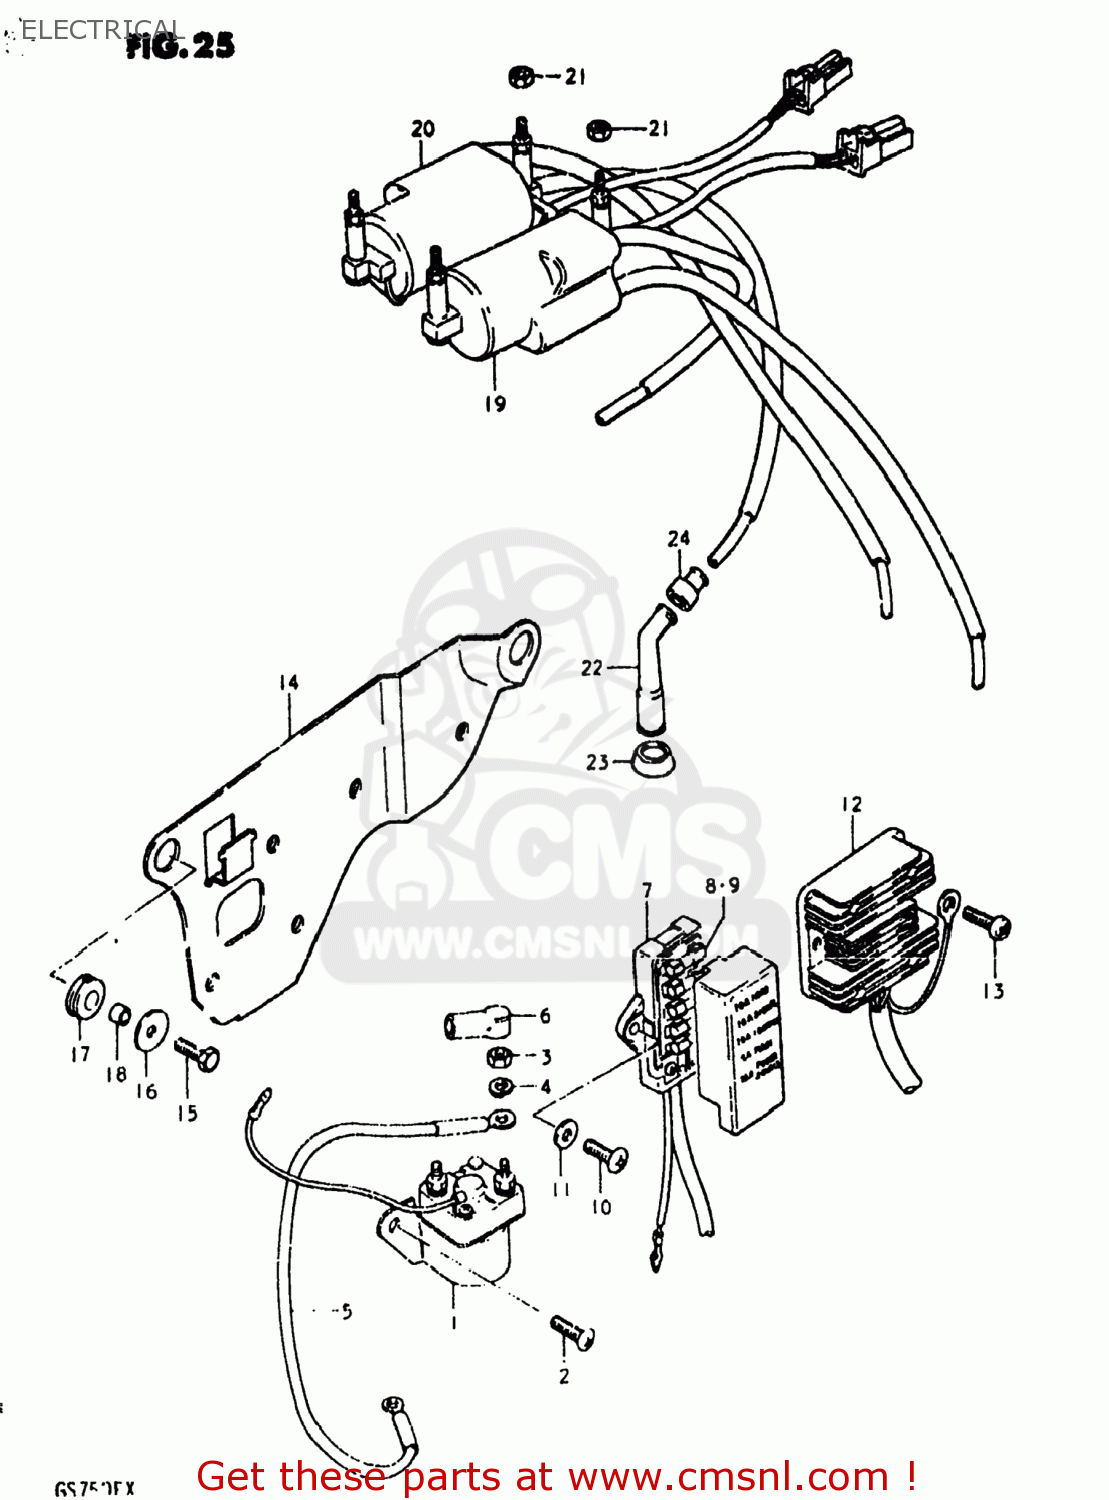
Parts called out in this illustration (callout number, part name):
1	RELAY ASSY,STARTING MOTOR
2	SCREW
3	NUT 6MM
4	LOCK WASHER
5	WIRE,STARTER MOTOR LEAD
6	CAP,STARTER RELAY
7	BOX ASSEMBLY,FUSE
8	FUSE(10A)
9	FUSE(15A)
10	SCREW
11	WASHER
12	RECTIFIER ASSEMBLY
13	SCREW 6X12
14	PLATE,ELECTRIC PARTS HOLDER
15	BOLT, UPPER
16	WASHER(6,5X22X1.6)
17	CUSHION
18	SPACER (7X9X7)
19	COIL ASSEMBLY,IGNITION
20	COIL ASSEMBLY,IGNITION
21	NUT
22	CAP ASSY,SPARK PLUG
23	SEAL,SPARK PLUG
24	SEAL,SPARK PLU
